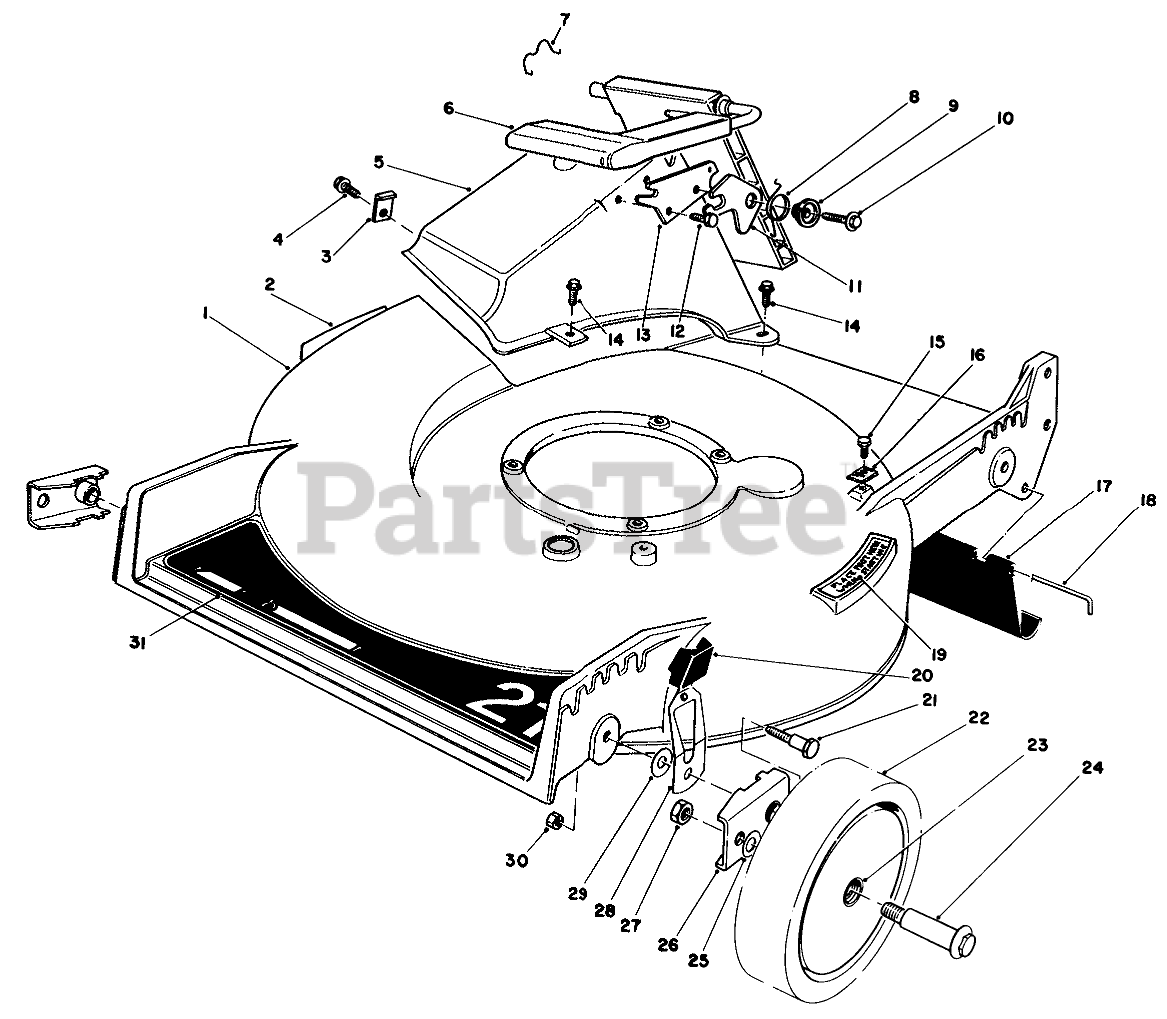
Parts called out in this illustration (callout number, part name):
1	Housing-21" (Incl. Ref. #2 & 19)
2	DECAL-DANGER
3	TUNNEL CLIP
4	SCREW
5	Tunnel Discharge
6	Discharge Door Assembly
7	DOOR RET SPRING
8	TORSION SPRING
9	DOOR SPACER
10	SCREW-HWH
11	SAFETY LATCH
12	SCREW-PLASTITE
13	DOOR LATCH PLATE
14	SCREW-HWH
15	SCREW-HWHTF
16	Cable Clamp
17	SHIELD-TRAILING
18	ROD-SHIELD
19	STEP PAD DECAL
20	KNOB-ARM
21	PIVOT SCREW
22	Wheel & Tire Assembly (Incl. Ref. #23)
23	BUSHING
24	WHEEL BOLT
25	WASHER
26	HP PIVOT ARM ASM
27	NUT-LOCK
28	Spring Arm
29	WASHER-PIVOT
30	NUT-LOCK, NI
31	DECK DECAL
